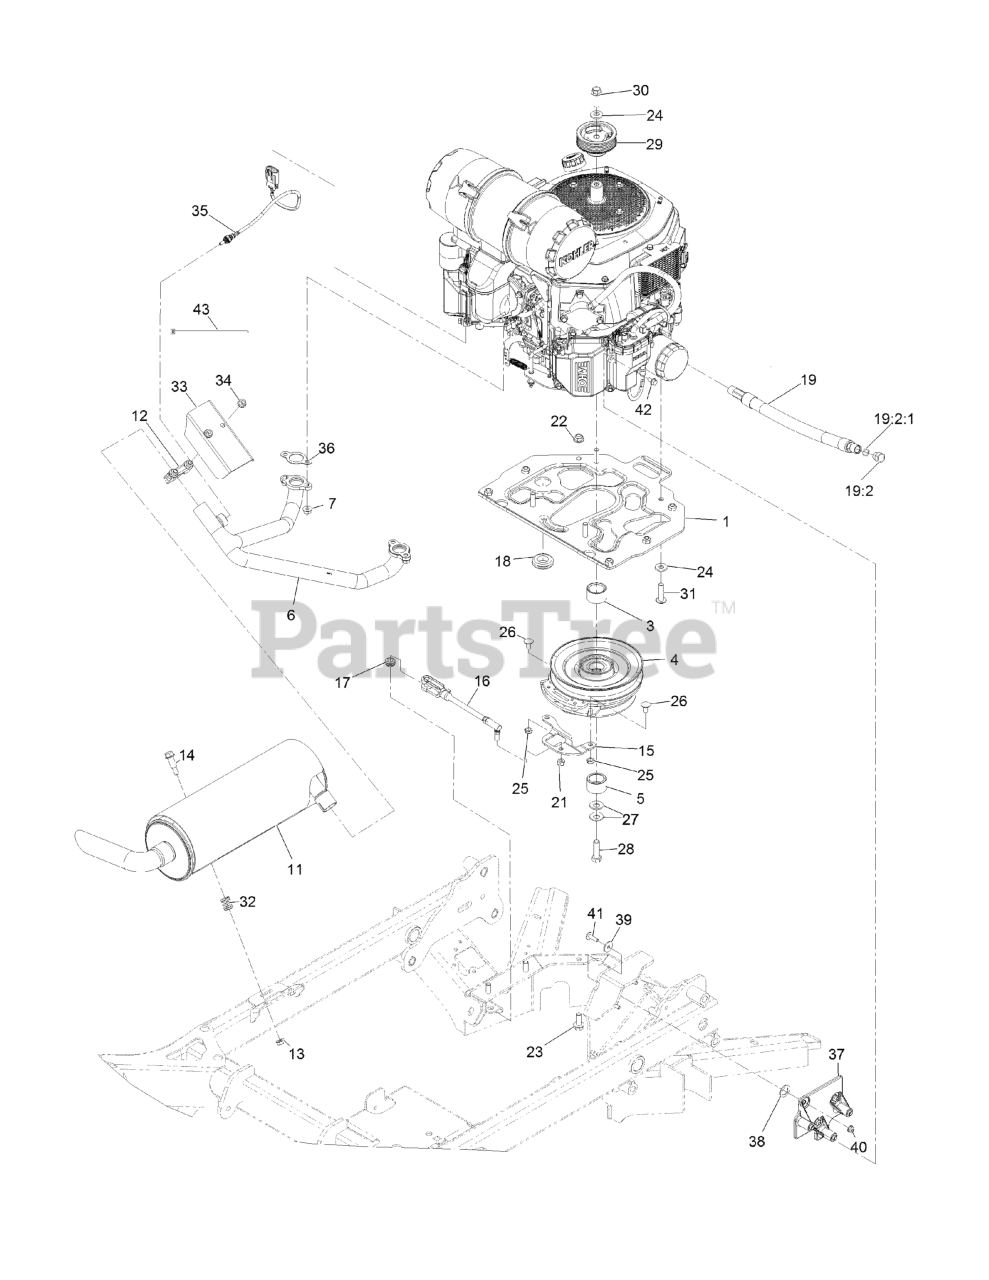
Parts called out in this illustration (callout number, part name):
1	PLATE, ENGINE
3	SPACER, CLUTCH
5	SPACER, CLUTCH
6	HEADER, KOHLER
7	NUT-FLANGE
12	CLAMP-MUFFLER
14	Bolt-Shoulder
15	STRAP, CLUTCH
16	ASM, CLUTCH ANCHOR
17	GROMMET
18	GROMMET
19	OIL DRAIN HOSE ASM
19:2	PLUG-HH
19:2:1	O-RING
21	NUT-LOCK
22	NUT-HF, NI
23	SCREW-HHF 3/8-16 X 1
24	WASHER-BELLEVILLE
25	NUT-LOCK, NI
26	SCREW-CARR
27	WASHER-SPRING
28	BOLT-HEX, TAP
29	PULLEY, CRANK
30	SCREW-HHF
31	SCREW-BHTF
32	SPRING, COMPRESSION
33	SHIELD, HEAT
35	SENSOR, MINI O2
36	GASKET-EXHAUST
37	Bracket-Pump, Fuel
38	Washer-Rubber
41	SCREW-TRUSS
42	SCREW-HHF
43	TIE-PLASTIC
